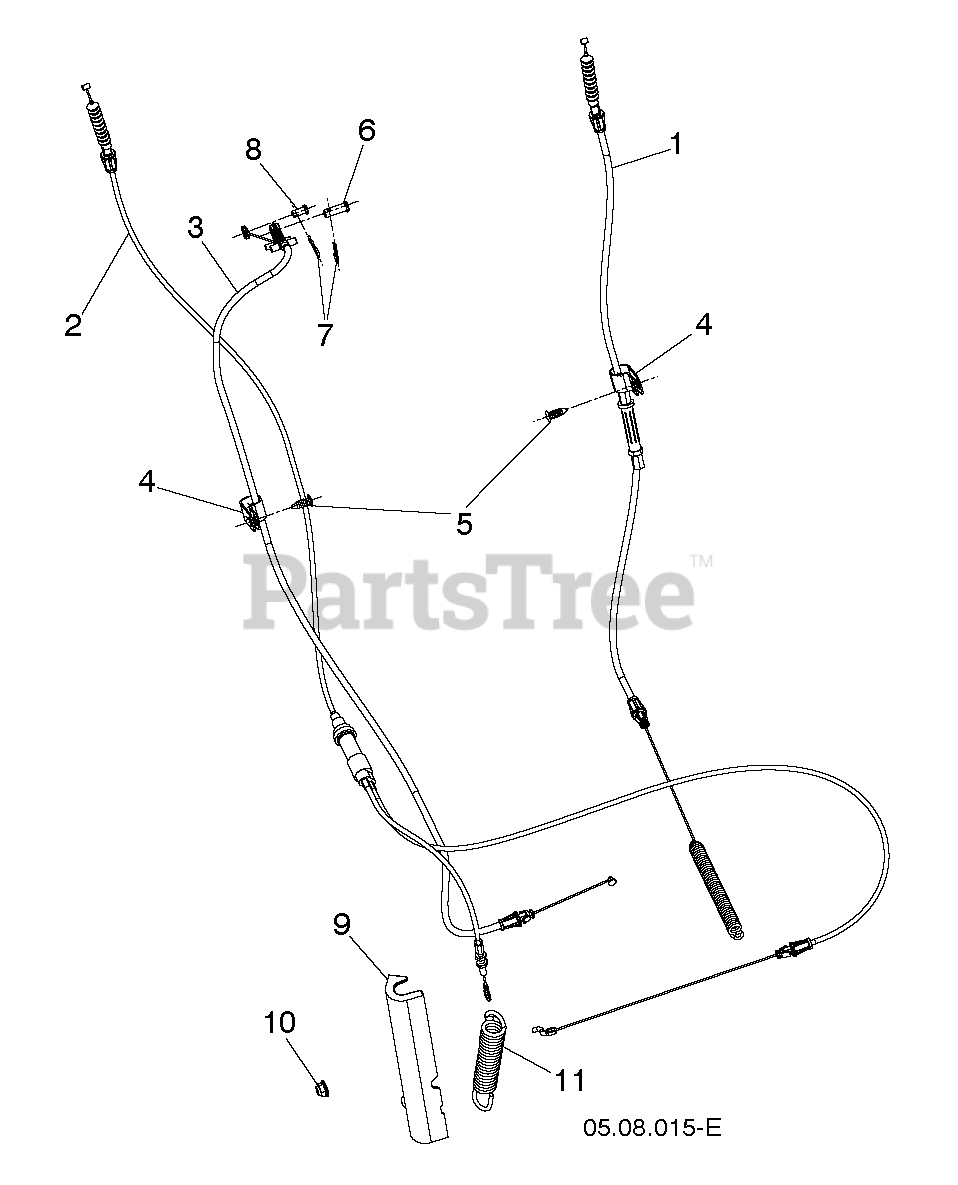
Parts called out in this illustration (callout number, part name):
1	Cables
2	CABLE IMPELLER
3	Cables
4	CLIP.CABLE.BLK
5	FASTENER.PUSH.O.250X0.783
6	PIN CLEVIS 5/16X.875
7	HAIRPIN.SOFT.ZINC.059X1.125
8	PIN CLEVIS .25 X .31
9	COVER AUGER CABLE
10	NUT HEXAGON FLANGE 5/16-18 ST
11	SPRING EXTENSION; AUGER EXTENS
